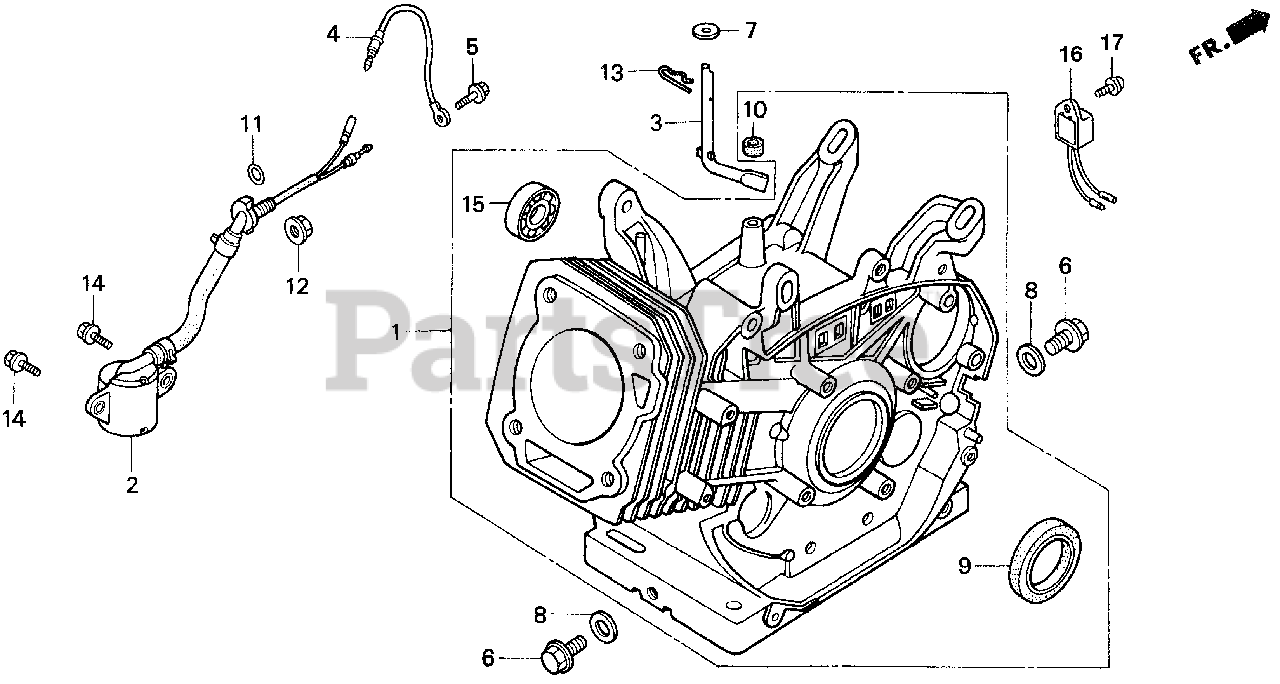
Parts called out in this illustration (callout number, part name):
1	CYLINDER ASSY. (ALERT)
2	SWITCH ASSY., OIL LEVEL
3	SHAFT, GOVERNOR ARM
4	SUB-HARNESS (NOT AVAILABLE)
5	BOLT, FLANGE (6X12) (CT200)
6	BOLT, DRAIN PLUG (12X15)
7	WASHER (8.2X17X0.8)
8	WASHER, DRAIN PLUG (12MM)
9	OIL SEAL (35X52X8)
10	OIL SEAL (8X14X5)
11	O-RING (13.5X1.5) (ARAI)
11	O-RING (14MM) (NOK)
12	NUT, FLANGE (10MM)
13	PIN, LOCK (10MM)
14	BOLT, FLANGE (6X12)
15	BEARING, RADIAL BALL (6202)
16	ALERT UNIT, OIL
17	BOLT, FLANGE (6X12) (CT200)
